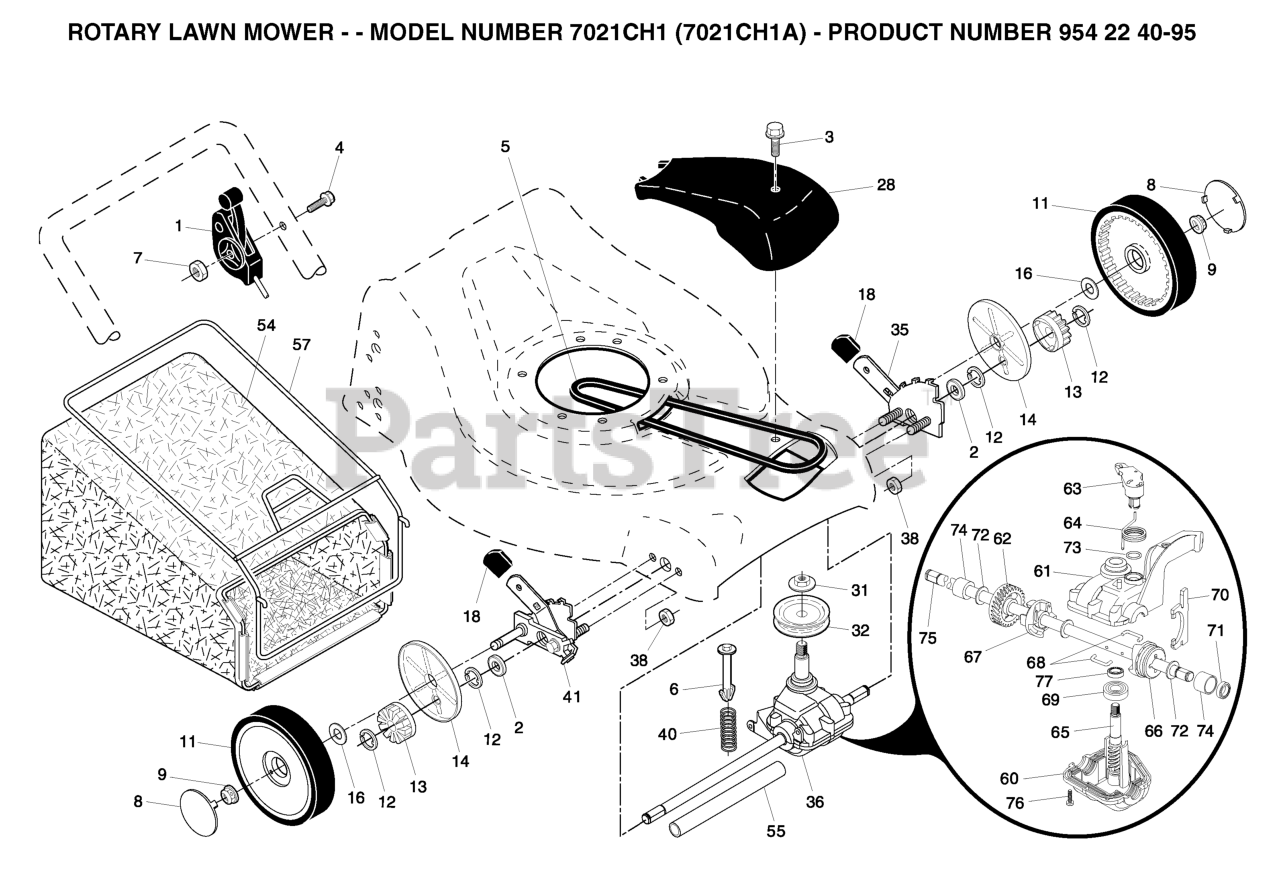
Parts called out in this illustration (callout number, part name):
1	DRIVE CONTROL 59.8 FWGD
2	BEARING, BALL
3	SCREW, HEX HD TAPPING #10-24 1
4	SCREW.PAN.HEAD
5	BELT.DRIVE.21FGD.1SPEED
6	SPRING RETAINER
7	NUT.HEX.FLANGE.1/4
8	HUBCAP
9	NUT
11	WHEEL.8X2.PR.LP.RAD.BLK
12	E-RING 7/16 RE
13	PINION GEAR
14	DUST COVER, WHEEL
16	WASHER FLUT
28	COVER.DRIVE.21.FWGD.GRAY
31	FLANGED LOCKNUT 3/8-16 ZINC
32	PULLEY, DRIVE
35	WHEEL ADJ ASM (L)
36	TRANSMISSION.21.HT.GWGD
38	LOCKNUT.NYLOC.1/4-20
40	SPRING.EXTENSION
41	KIT.ADJUSTER.ASM.(151514).RT
54	GBAG.32510010.BLK.GEN.SERVICE
55	DRIVESHAFT COVER
57	BAG FRAME
60	LOWER CASE
61	UPPER CASE
62	GEAR.27.TEETH.WALK.MOWER
63	LEVER, CLUTCH
64	SPRING, RETURN
65	SHAFT INPUT (13041)
66	DOG, MOVABLE (11032)
67	DOG, FIXED GT11031
68	WIRE, FORMED (15966)
70	FORK, SHIFT
71	SEAL.OUTPUT.SHAFT
73	SEAL, CASE O-RING
75	SHAFT OUTPUT (12159)
77	SEAL INPUT SHAFT
